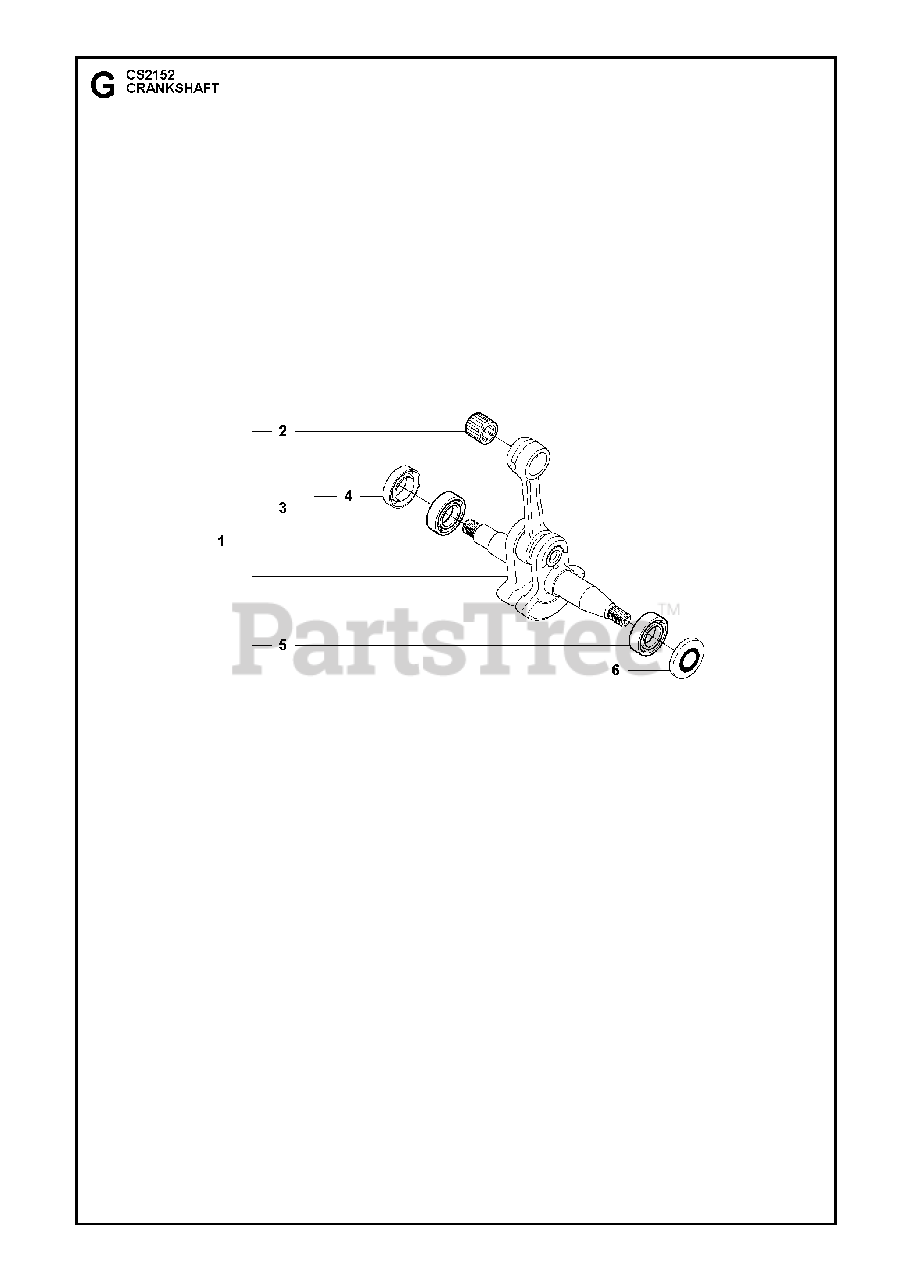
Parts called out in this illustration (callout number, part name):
1	CRANKSHAFT
2	RP SUPPORT BUSHING
3	BALL BEARING
4	RADIAL SEAL
5	BALL BEARING-6202-C3 SKF
6	SEAL RING
